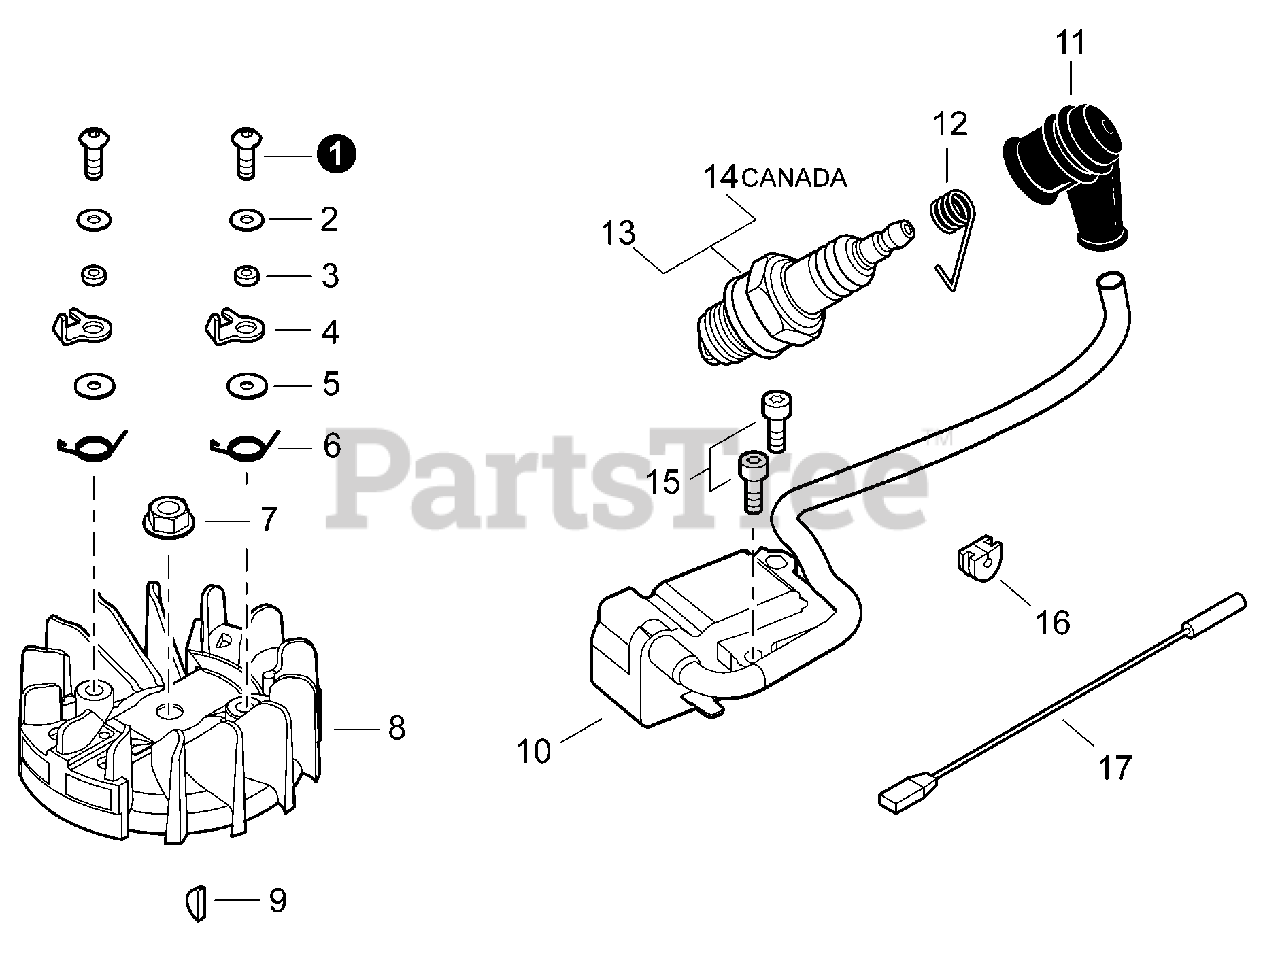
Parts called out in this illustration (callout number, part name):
1	BOLT 5×14
2	WASHER 5.5×12×0.8
5	WASHER 5.5×16×0.8
6	SPRING, TORSION
7	NUT, FLANGE
8	FLYWHEEL
9	KEY, WOODRUFF
10	COIL, IGNITION
11	CAP, SPARK PLUG
12	TERMINAL, SPARK PLUG
13	SPARK PLUG - BPM8Y
14	SPARK PLUG - BPMR8Y
15	BOLT, TORX 4
17	LEAD L= 85 mm
